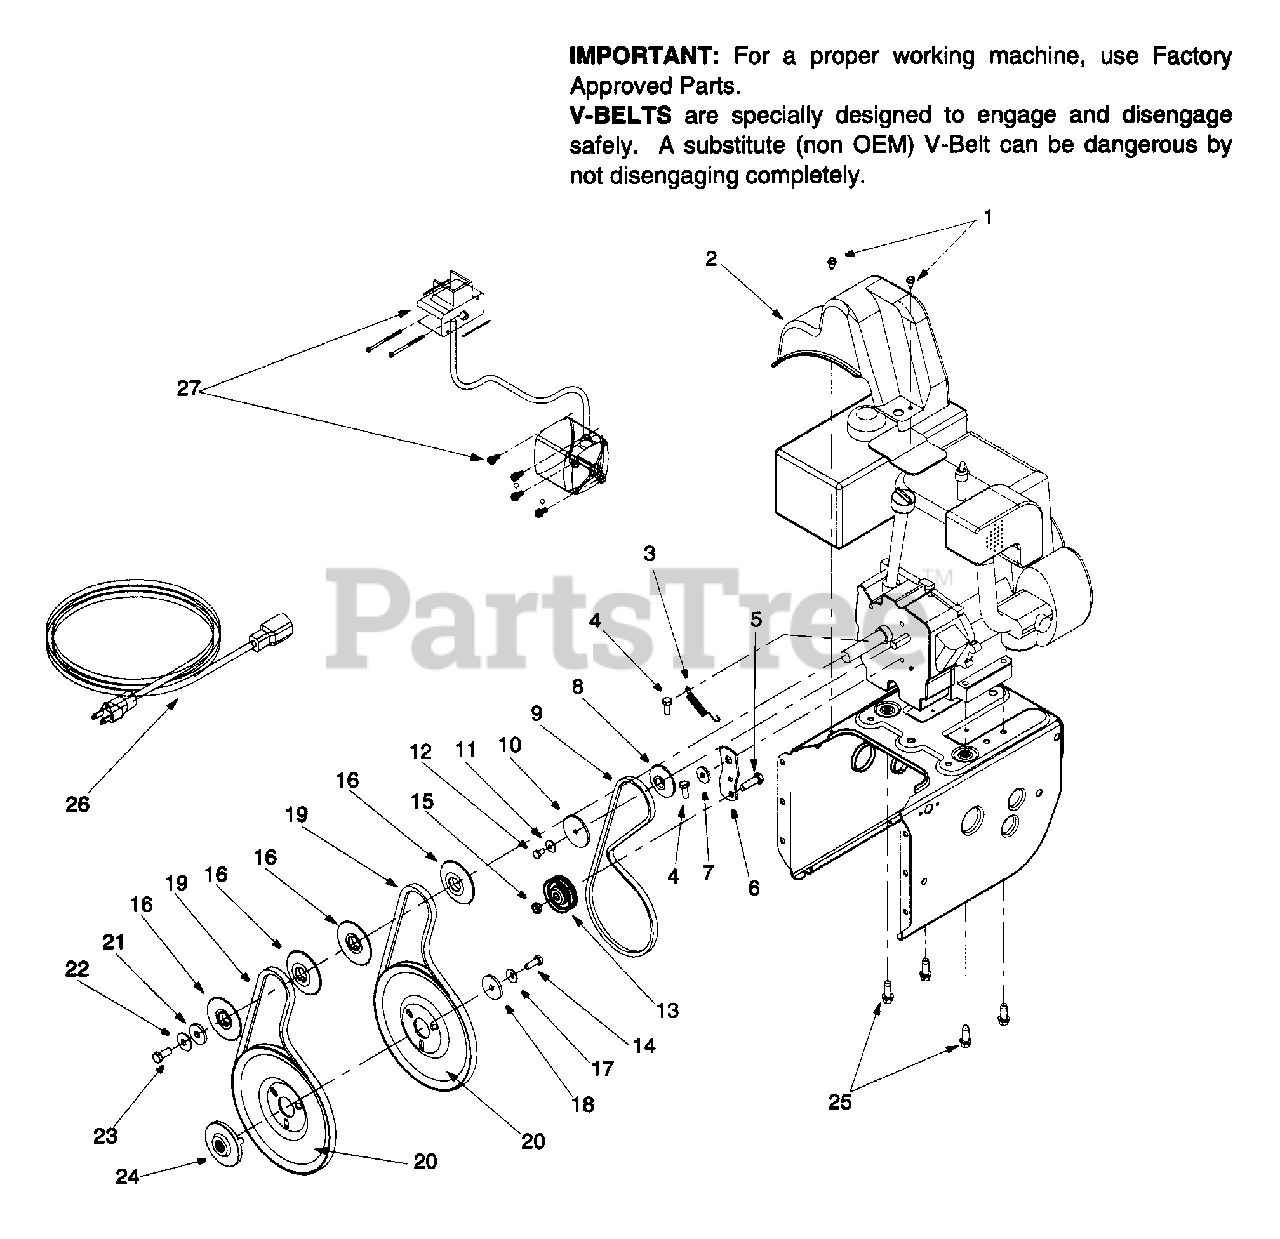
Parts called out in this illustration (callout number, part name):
1	Hex Washer Screw 1/4-20 x .50
2	Belt Cover
3	Extension Spring
4	Hex Screw 5/16-24 x .75
5	Hex Cap Screw 3/8-16 x 1.25
8	Pulley Half
9	V-Belt
10	Pulley Half
11	Bell Washer
12	Hex Cap Screw 1/4-28 x .50
13	Flat Idler
14	Lock Hex Cap Screw 5/16-24
15	Lock Jam Nut 3/8-16
16	Pulley Half
17	Bell Washer
18	Flat Washer
19	Belt
20	Auger Pulley
21	Flat Washer 3/8 x 1.25 OD
22	Bell Washer
23	Hex Cap Screw 3/8-24
24	Adapter Pulley
25	Hex Screw 3/8-16 x 1.0
26	Extension Cord
27	Electric Start
